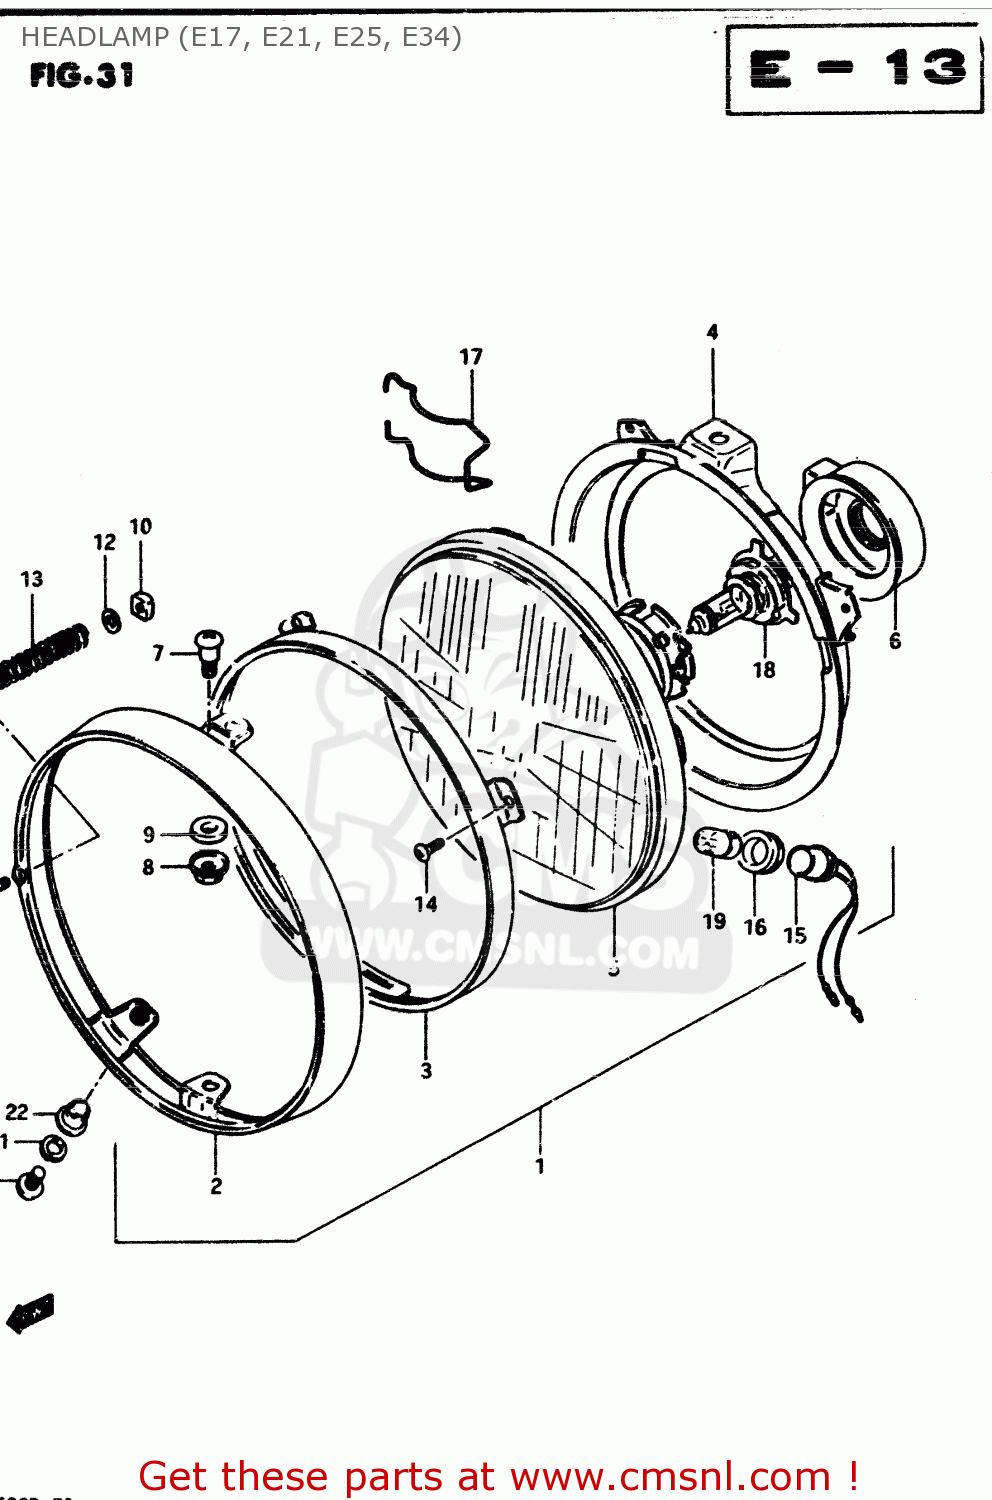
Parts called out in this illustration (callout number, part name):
1	HEADLAMP ASSY
2	RIM
3	RETAINER
4	RING,HEADLAMP UNIT
5	UNIT,HEAD LAMP
6	COVER,HEADLAMP SOCKET
7	SCREW
8	NUT,ADJUSTING
9	SPACER
10	NUT
11	SCREW
12	WASHER
13	SPRING,HEADLAMP ADJUST
14	SCREW
15	SOCKET
16	JOINT,RUBBER
17	CLAMP,HEADLAMP SOCKET
18	BULB(12V60/55W,H4)
19	BULB(12V4W)
20	SCREW
21	WASHER,LOCK
22	WASHER
